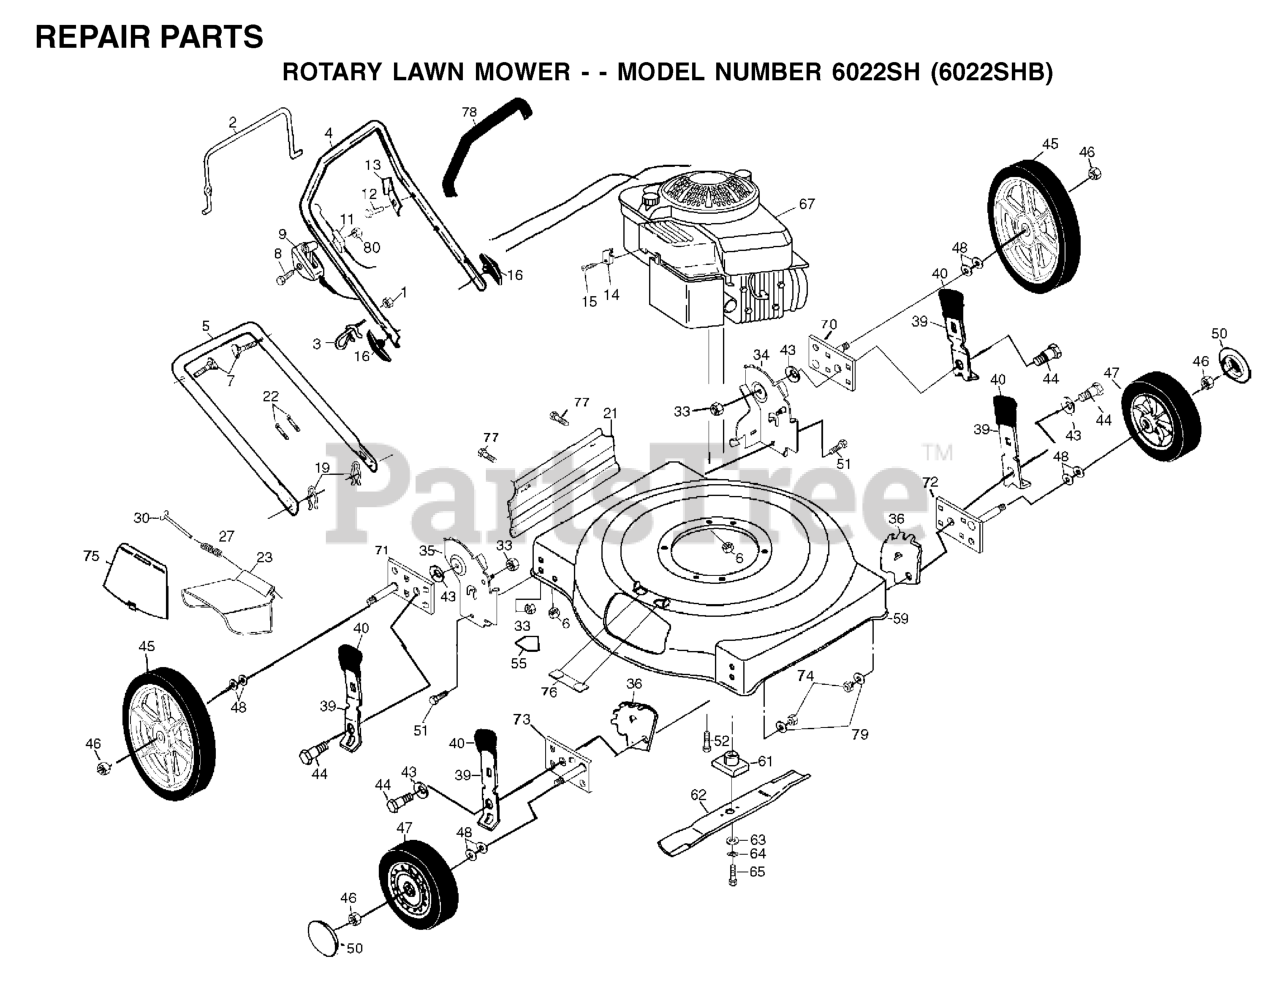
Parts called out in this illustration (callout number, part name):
1	NUT
3	ROPE, GUIDE
5	HANDLE.LOWER.BLACK
6	NUT
7	HANDLE BOLT
8	SCREW 1/4-20 X 2.12
9	THROTTLE TRIGGER
11	ENGINE ZONE CONTROL
12	TAPPING SCREW
13	BRACKET UPSTOP
14	WASHER
15	SCREW.HEX.HEAD.WASHER.10-16
16	HANDLE KNOB
19	HAIRPIN COTTER
21	REAR DEFLECTOR, POULAN PR6N22
22	TIE GUIDE
27	TORSION SPRING
33	LOCKNUT
34	BRACKET, WHEEL SUPPORT(L)
35	BRKT ASM,HANDLE
36	WHEEL BRACKET ADJUSTER
39	REPL BY 532 1683-60
43	WASHER
44	SHOULDER BOLT
45	WHEEL.14X2.PR.SP.RAD.GY
46	HEX FLANGE LOCKNT
47	WHEEL.8X2.PR.LP.RAD.GREY
48	WAVE WASHER
50	CAP.HUB.BLACK.WALK
51	BOLT
52	BOLT 3/8-16X1-1/8
55	DECAL HYT
61	BLADE ADAPTOR
63	WASHER,HARDEN
64	LOCKWASHER
65	SCREW, HEX HD 3/8-24 X 1-3/8
72	AXLE ARM ASM (L)
73	AXLE ARM ASM
74	NUT.LOCK.5/16-18
75	MULCHER PLATE
77	BOLT.HEX.1/4.X.3/4.DICHROMATE
78	GRIP.HANDLE.FOAM
79	WASHER
80	NUT
